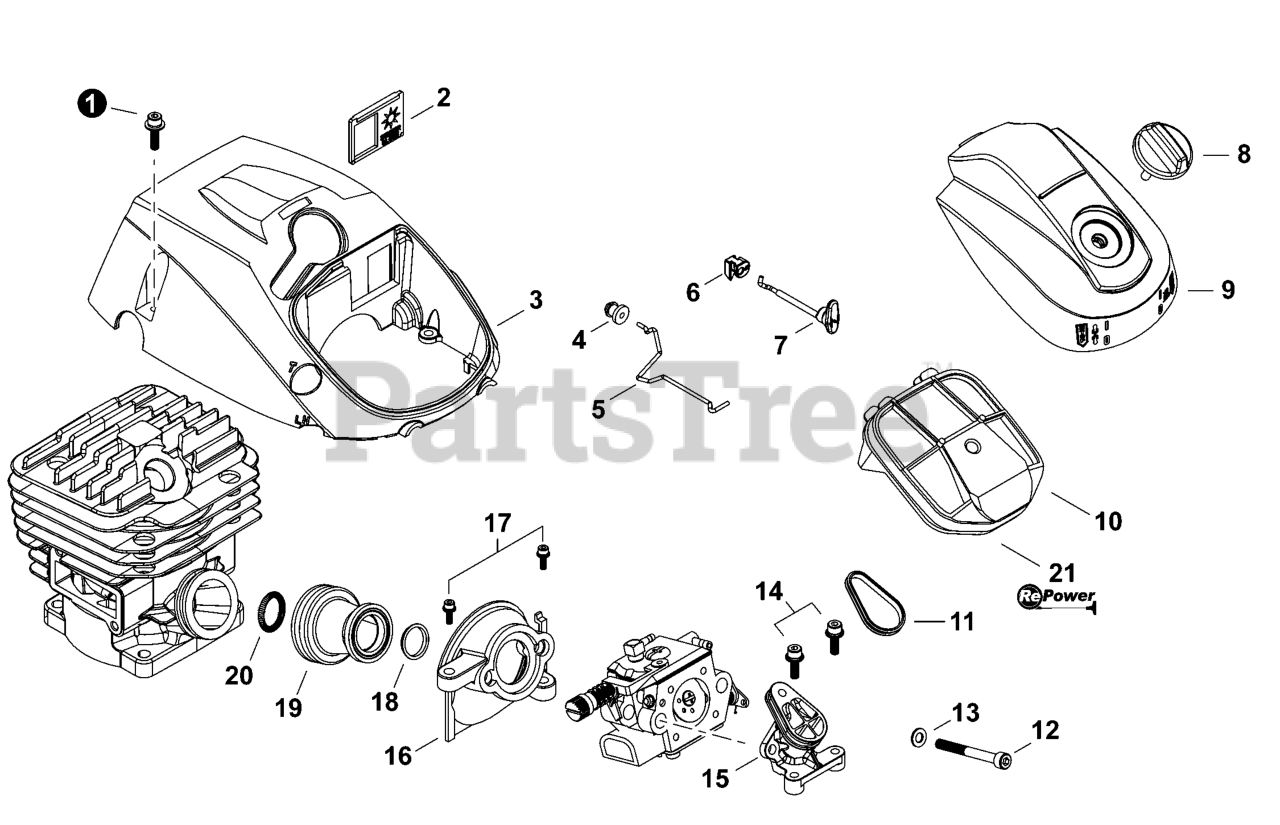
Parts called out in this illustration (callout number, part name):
1	BOLT M4x16
2	PLATE, SHUTTER
3	COVER, ENGINE
4	GROMMET
5	ROD, THROTTLE
6	GROMMET, CHOKE
7	ROD, CHOKE
8	THUMBSCREW
9	COVER, AIR FILTER
10	FILTER ASSY, AIR, FLOCKED
12	BOLT M5x48
13	WASHER, FLAT 5.5x10x0.8
14	BOLT M4x16
15	ADAPTOR, AIR FILTER
16	INSULATOR, INTAKE
17	BOLT M4x16
18	COLLAR 16
19	BELLOWS, INTAKE
20	SPRING, TENSION
21	TUNE-UP KIT - REPOWER
